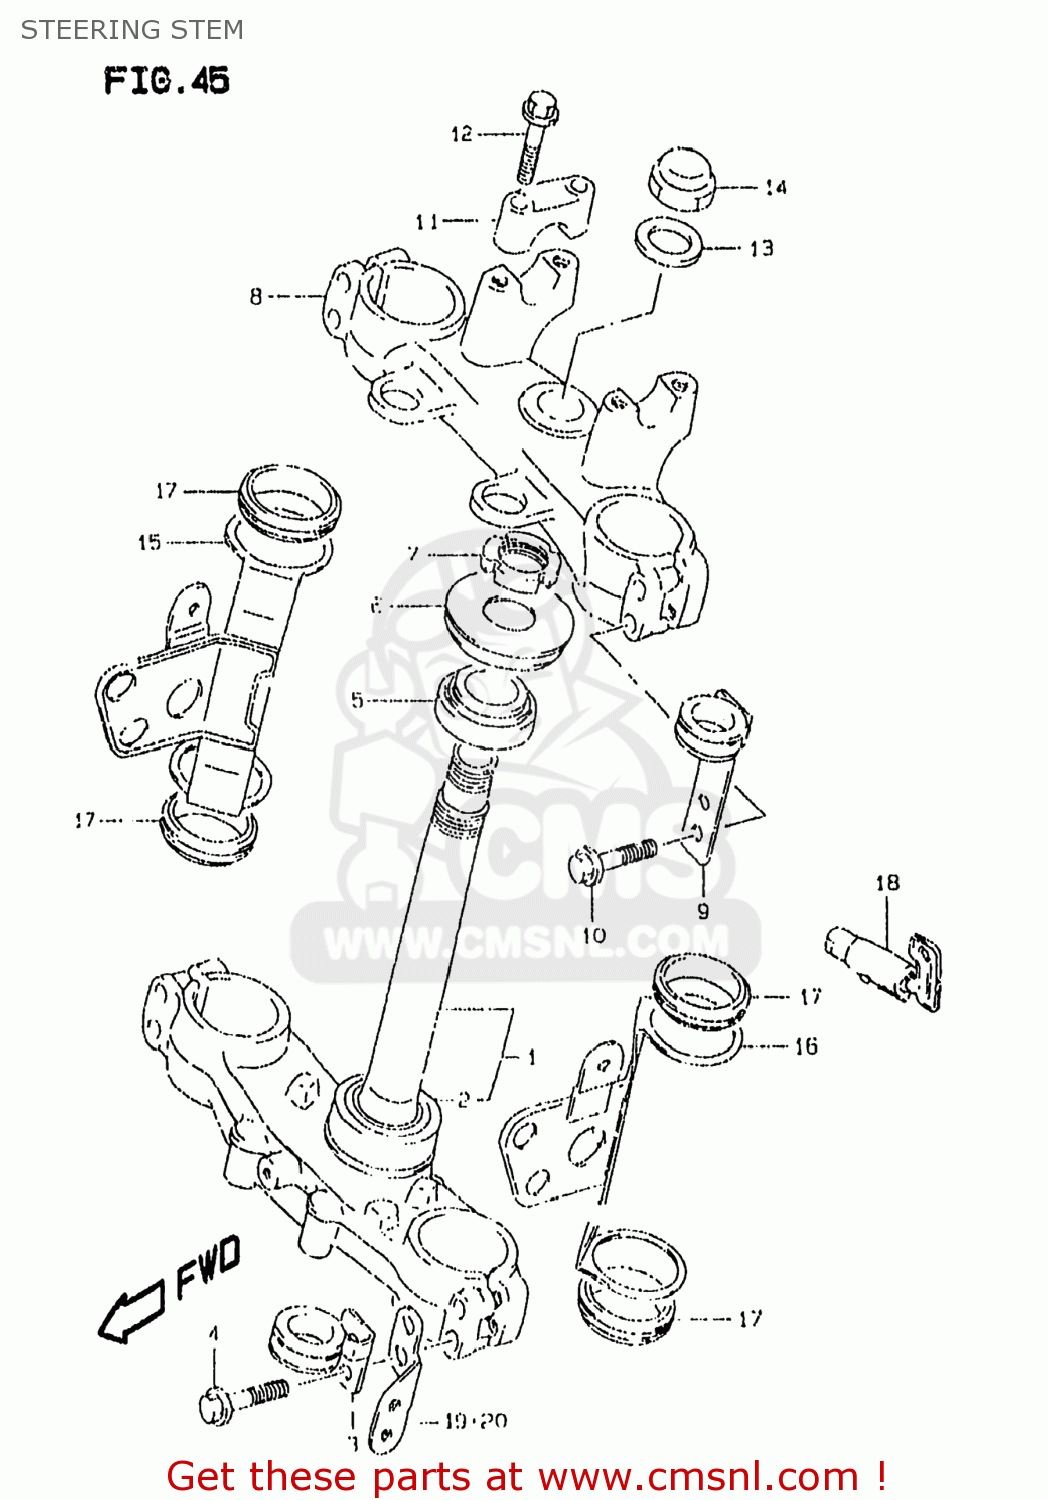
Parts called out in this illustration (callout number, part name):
1	STEM,STEERING
2	BEARING(30X55X17)
3	GUIDE,CABLE LWR,L
4	BOLT
5	BEARING(25X47X15)
6	SEAL,STEERING UPR DUST
7	NUT,STEERING STEM
8	HEAD,STEERING STEM
9	GUIDE,CABLE,LEFT,UPPER
10	BOLT
11	HOLDER,HANDLE UPR
12	BOLT
13	WASHER
14	NUT,CAP
15	BRACKET,HEADLAMP HOUSING,R
16	BRACKET,HEADLAMP HOUSING,L
17	DAMPER,HEADLAMP HSG BRACKET
18	LOCK ASSY,STEERING(NEIMAN)
19	BRACKET,FRONT SIDE REFLECTOR
20	BRACKET,FR SIDE REFLECTOR,L
